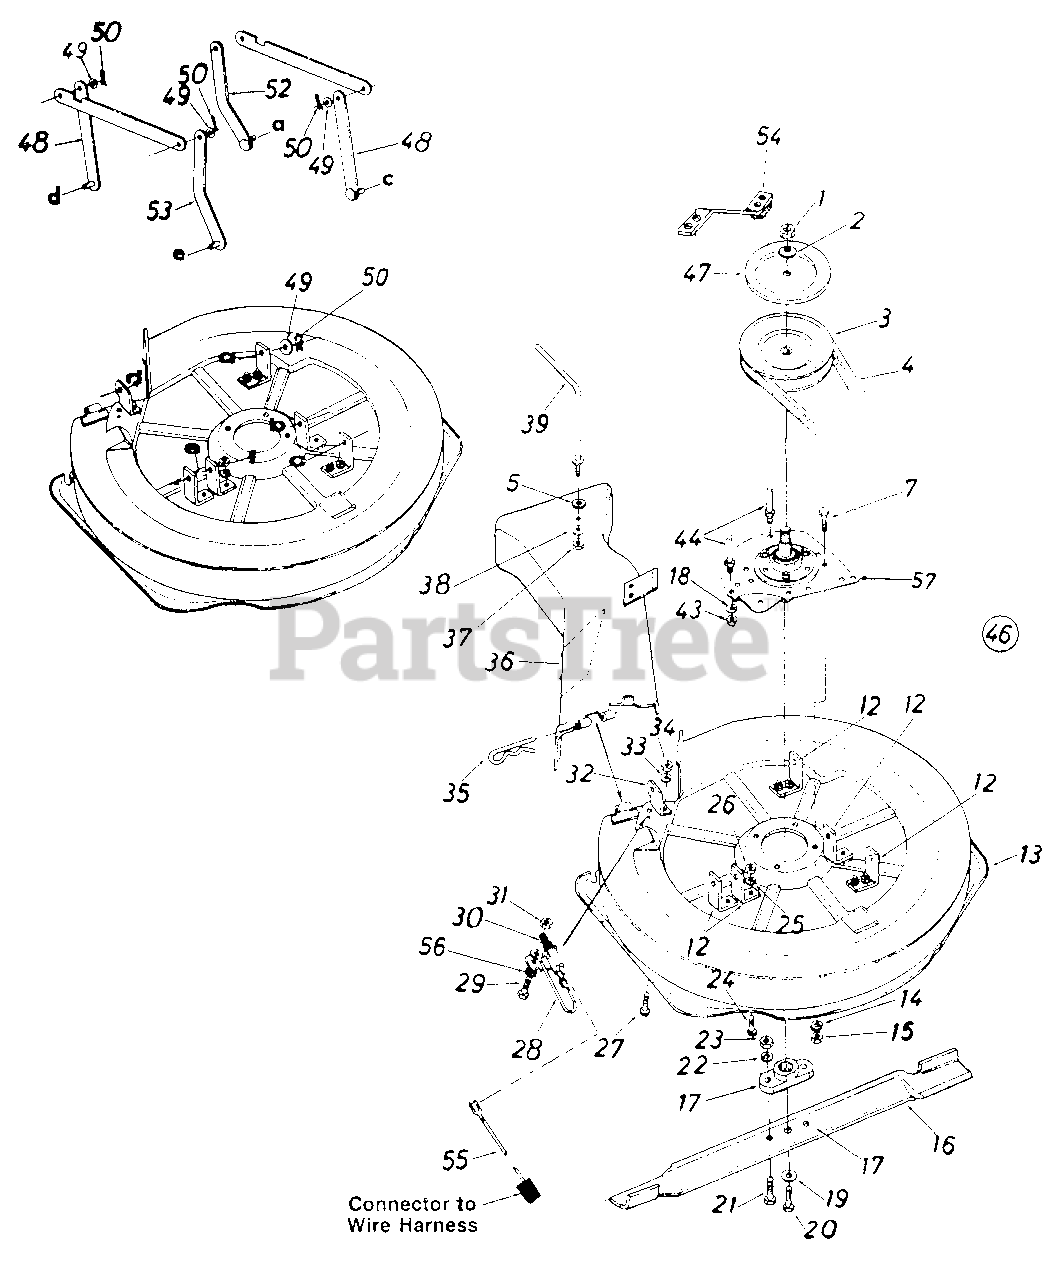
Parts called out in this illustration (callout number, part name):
1	Hex Jam Nut 5/8-18 Thd.
2	Bell-Wash. .630" I.D. x 1.25"
5	Fl-Wash. .344" I.D. x 1.12" O.D.
7	Hex Bolt 5/16-18 x .75" Lg.
12	Hanger Bracket
15	Hex Nut 5/16-18 Thd.
16	30" High Lift Blade-R.H.
17	Blade Adapter
18	L-Wash. 3/8" I.D.
19	Bell-Wash. .391' I.D. x 1.38" O.D.
20	Hex Bolt 3/8-24 x 1.00" Lg.
21	Hex Bolt 5/16-24 x 1.00" Lg.
22	L-Wash. 5/16" I.D.
23	Hex Nut 5/16-24 Thd.
24	Hex Sems Bolt 5/16-18 x .62" Lg.
25	L-Wash. 5/16" I.D.
26	Hex Nut 5/16-18 Thd.
27	Truss Mach. Scr. 5/16-18 x .75" Lg.
28	Electrical Wire
29	Hex Bolt 1/4-20 x .50" Lg.
30	Safety Switch
31	Hex Nut 1/4-20 Thd. I
32	Angle Hanger Brkt.
33	L-Wash. 5/16" I.D.
34	Hex Nut 5/16-18 Thd.'
35	Internal Cotter Pin
36	R.D. Chute Deflector
37	Hex L-Nut 5/16-18 Thd.
38	L-Wash. .32" I.D. x .62" O.D.
39	90ø Rod 5/16-18 Thd.
43	Hex Jam Nut 3/8-16 Thd.
44	Stud 3/8-16 x 3.0" Lg.
46	30" R.D. Deck Ass'y. Comp.
47	Brake Disc
48	Link Deck Hanger Ass'y.
49	Fl-Wash. .53" I.D. x 93' O.D.
50	Inter. Cotter Pin .50" Dia.
54	Blade Brake Ass y.
55	Wire Lead
56	L-Wash. 1/4" I.D.
57	Blade Spindle Ass'y. Comp.
